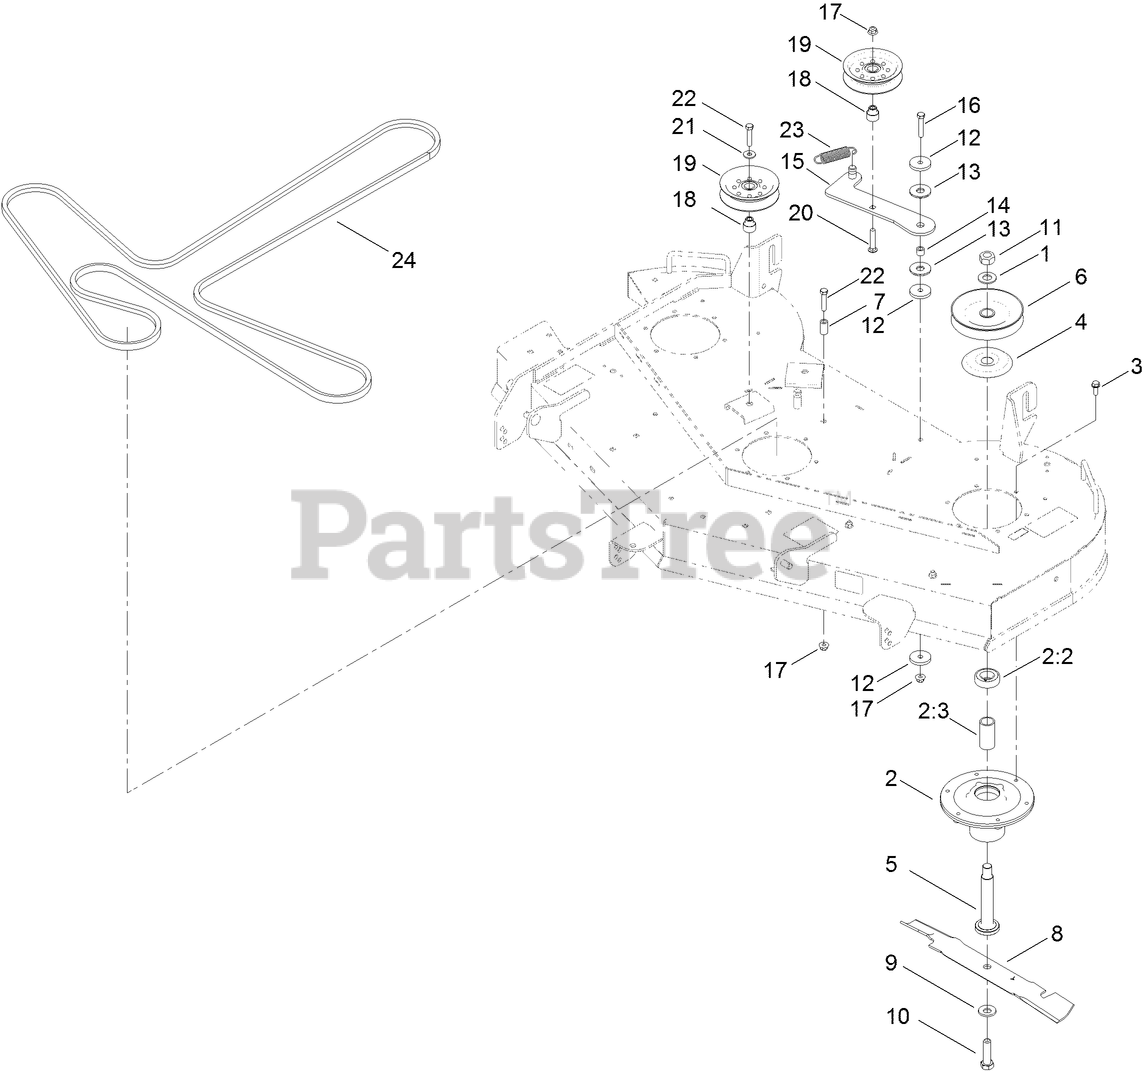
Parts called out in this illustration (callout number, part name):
1	WASHER
2	SPINDLE ASM
2:2	BEARING-BALL
2:3	SPACER-BEARING
3	SCREW-TAPTITE
4	SHIELD-BEARING
5	SHAFT-SPINDLE
6	PULLEY
7	SPACER
8	BLADE-MULCH, 18.75 INCH
9	WASHER-BELLEVILLE
10	SCREW-BLADE
11	NUT-HEX
12	WASHER-PLAIN
13	WASHER-FRICTION, COMPOSITE
14	BUSHING-LEVER, LIFT
15	ARM-IDLER
16	SCREW-HH
17	NUT-HF, NI
18	BUSHING-IDLER
20	SCREW-CARR
21	WASHER-HARDENED
22	SCREW-HH
23	SPRING-EXTENSION
